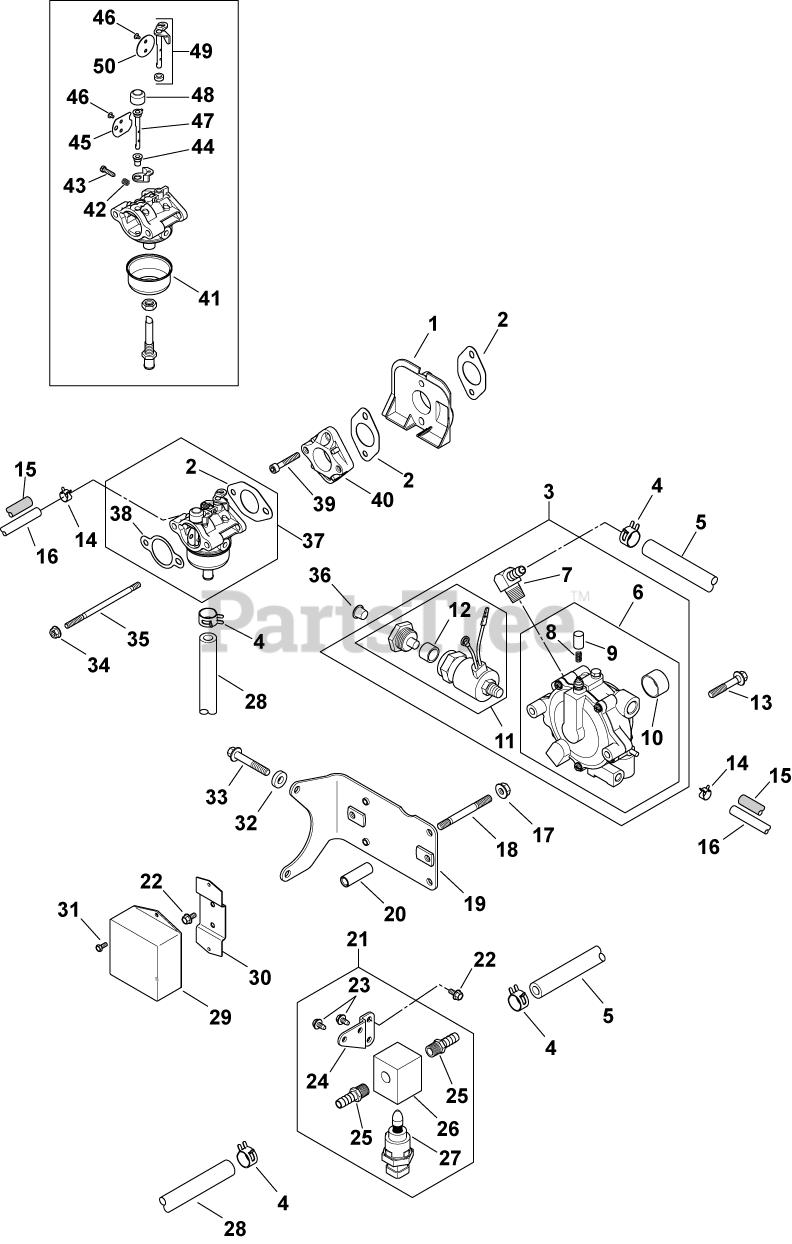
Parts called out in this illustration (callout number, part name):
1	DEFLECTOR, HEAT
2	GASKET, CARBURETOR
3	REGULATOR - DISCONTINUED
4	CLAMP, SPRING HOSE
5	LINE, LP FUEL
6	REGULATOR, 2 STAGE FUEL-USE 24 403 23-S
7	FITTING, 90 BARBED
8	SPRING, ANTI-TAMPER
11	SOLENOID, 12VDC LOCKOFF
12	FILTER, DRY FUEL
13	SCREW, FLG M8X1.25X45
14	CLAMP, HOSE
15	SLEEVE, INSULATING 14"
16	LINE, FLEXIBLE FUEL - DISCONTINUED
17	NUT, FLG M8X1.25
18	STUD, M8X1.25X133-USE 25 755 54-S
19	BRACKET, REGULATOR - DISC.
21	MIXER ASSEMBLY - DISCONTINUED
22	SCREW, HVY FLG M5X.8X10
23	SCREW, FLG THD FRM M5X.8X10
24	BRACKET, VALVE ASSEMBLY
25	FITTING - DISCONTINUED
26	MIXER, VALVE - DISCONTINUED
27	ACTUATOR, LINEAR - DISCONTINUED
28	LINE, LP FUEL - DISCONTINUED
29	CONTROL UNIT, ELECTRONIC - DISCONTINUED
30	BRACKET, ECU
31	SCREW, THD FRM M4X0.7X10
32	WASHER, FLAT 11/32"
33	SCREW, FLG M8X1.25X50
34	NUT, FLG M6X1.0
35	STUD,M6X1.0X116
36	PLUG, CAP 1/4 INCH
37	KIT, CARBURETOR - DISCONTINUED
38	GASKET, AIR CLEANER BASE
39	SCREW, SKT CAP M6X1.0X35
40	ADAPTER, CARBURETOR
44	BUSHING, CHOKE
45	PLATE, CHOKE
46	SCREW, VALVE
47	SHAFT, CHOKE
48	CAP, CHOKE LEVER
49	SHAFT, THROTTLE
